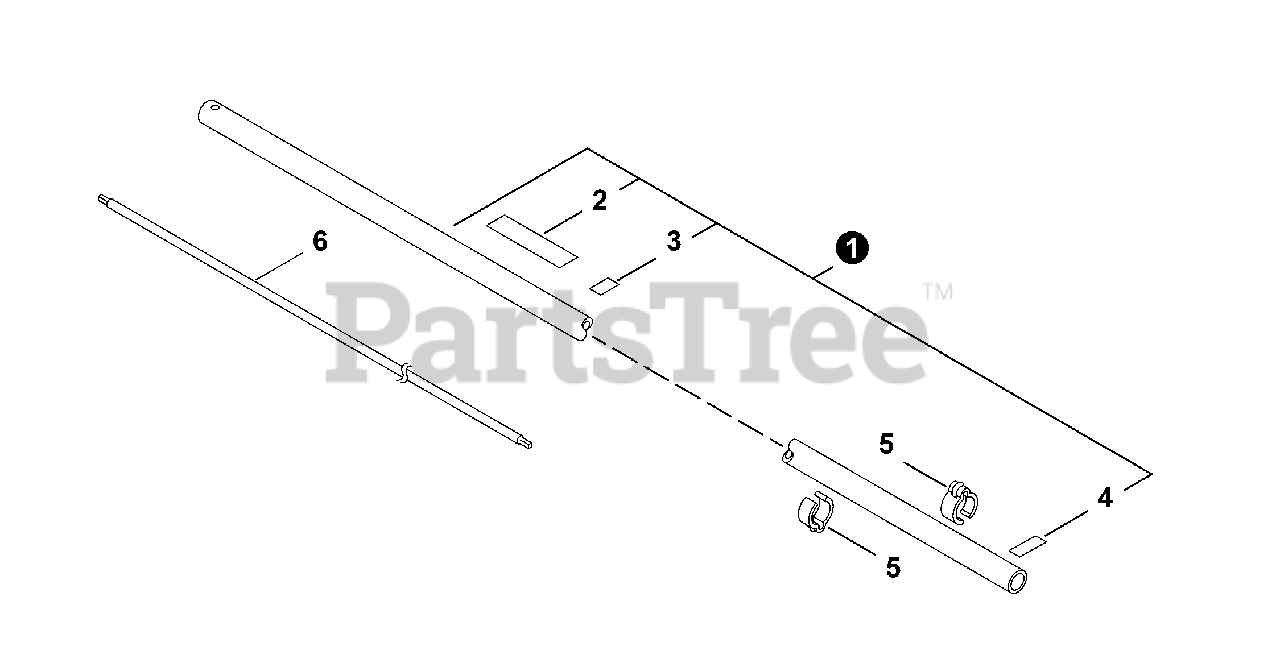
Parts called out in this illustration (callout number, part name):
1	MAIN PIPE ASSY
2	LABEL, CAUTION (BLADE CAPABLE)
3	LABEL, HANDLE
4	LABEL - ALIGNMENT
5	CLIP, CABLE 25 MM
6	MAINSHAFT
